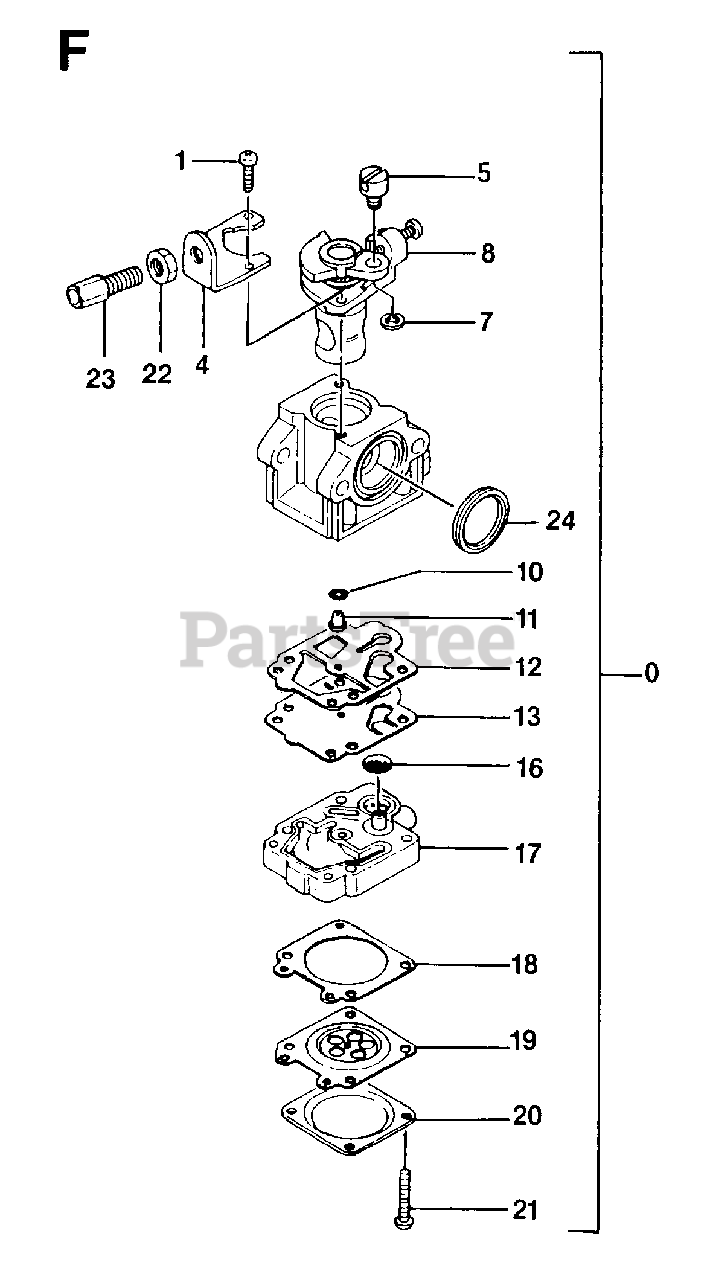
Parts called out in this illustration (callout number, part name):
7	RETAINING RING
19	METERING DIAPHRAGM
20	DIAPHRAGM COVER
22	CABLE ADJUST NUT
24	CLEANER GASKET
